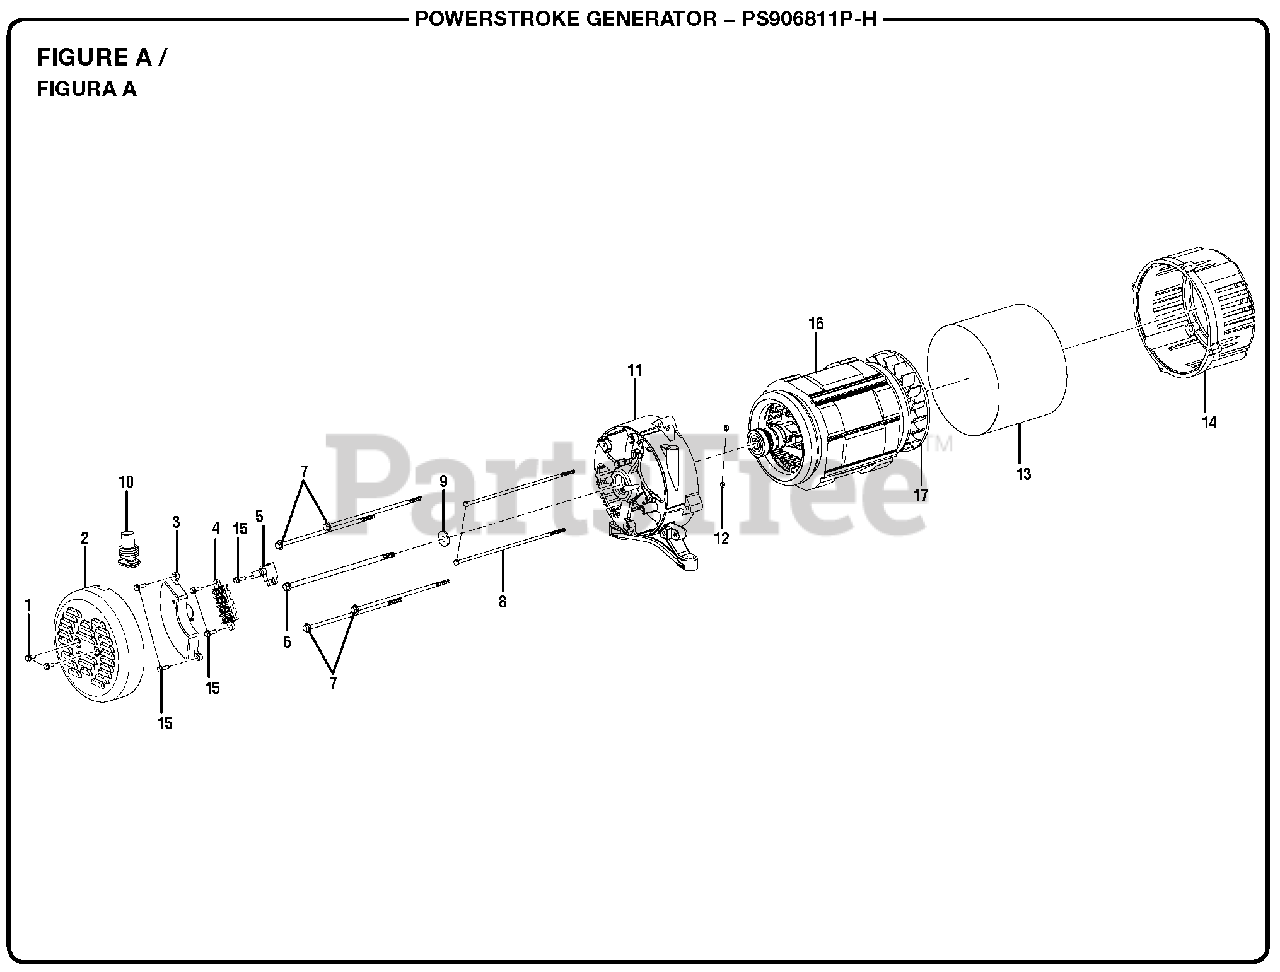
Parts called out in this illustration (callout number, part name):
1	Bolt (M5 x 12 mm, Hex Hd.)
2	Brush Cover
3	Automatic Voltage Regulator
4	Terminal Block
5	Brush Assembly
6	Bolt (5/16-24 x 235 mm, Hex Washer Hd.)
7	Bolt (M6 x 188 mm, Hex Washer Hd.)
8	Bolt (M5 x 210 mm, Hex Washer Hd.)
9	Washer (8 x 26 x 3t)
10	Rubber Boot
11	Bearing Housing
12	Hex Nut (M5)
13	Generator Head Cover
14	Adaptor Housing
15	Bolt (M5 x 16 mm, Hex Hd.)
